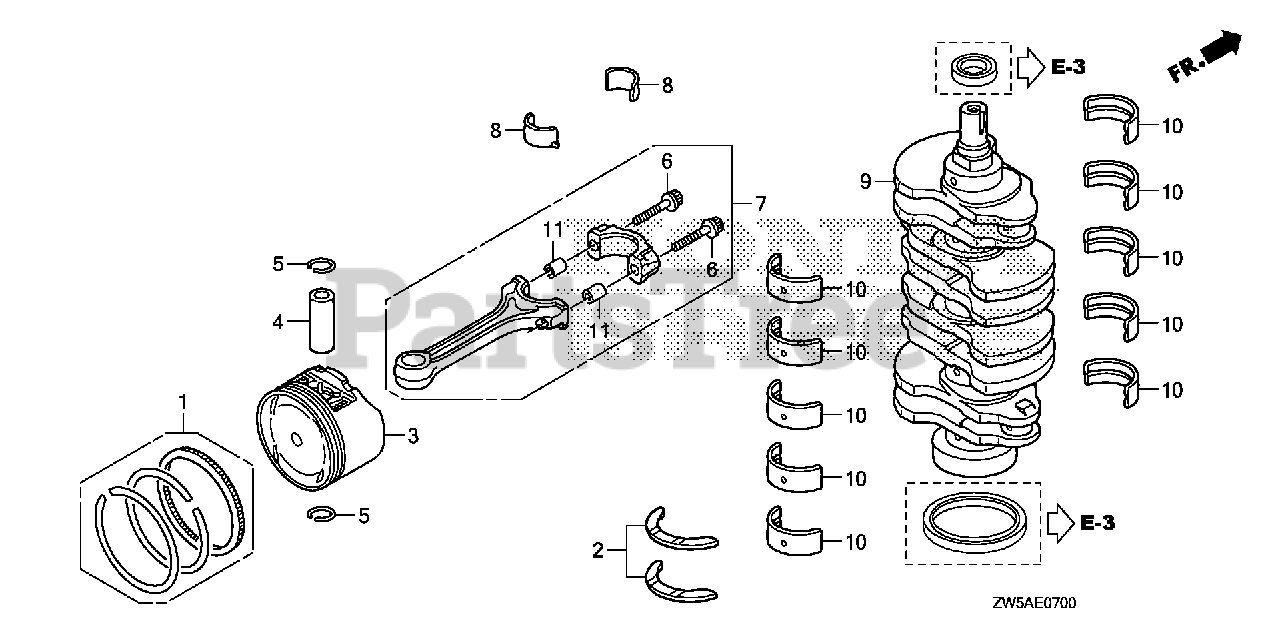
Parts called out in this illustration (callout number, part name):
1	RING SET, PISTON (STD)
2	WASHER SET, THRUST (DAIDO)
4	PIN, PISTON
5	CLIP, PISTON PIN
6	BOLT, CONNECTING ROD
7	ROD, CONNECTING
8	BEARING A, CONNECTING ROD (BLUE) (DAIDO)
8	BEARING B, CONNECTING ROD (BLACK) (DAIDO)
8	BEARING C, CONNECTING ROD (BROWN) (DAIDO)
8	BEARING D, CONNECTING ROD (GREEN) (DAIDO)
8	BEARING E, CONNECTING ROD (YELLOW) (DAIDO)
8	BEARING F, CONNECTING ROD (PINK) (DAIDO)
8	BEARING G, CONNECTING ROD (RED) (DAIDO)
9	CRANKSHAFT
10	BEARING A, MAIN (BLUE) (TAIHO)
10	BEARING B, MAIN (BLACK) (TAIHO)
10	BEARING C, MAIN (BROWN) (TAIHO)
10	BEARING D, MAIN (GREEN) (TAIHO)
10	BEARING E, MAIN (YELLOW) (TAIHO)
10	BEARING F, MAIN (PINK) (TAIHO)
11	PIN, DOWEL (10X12)
